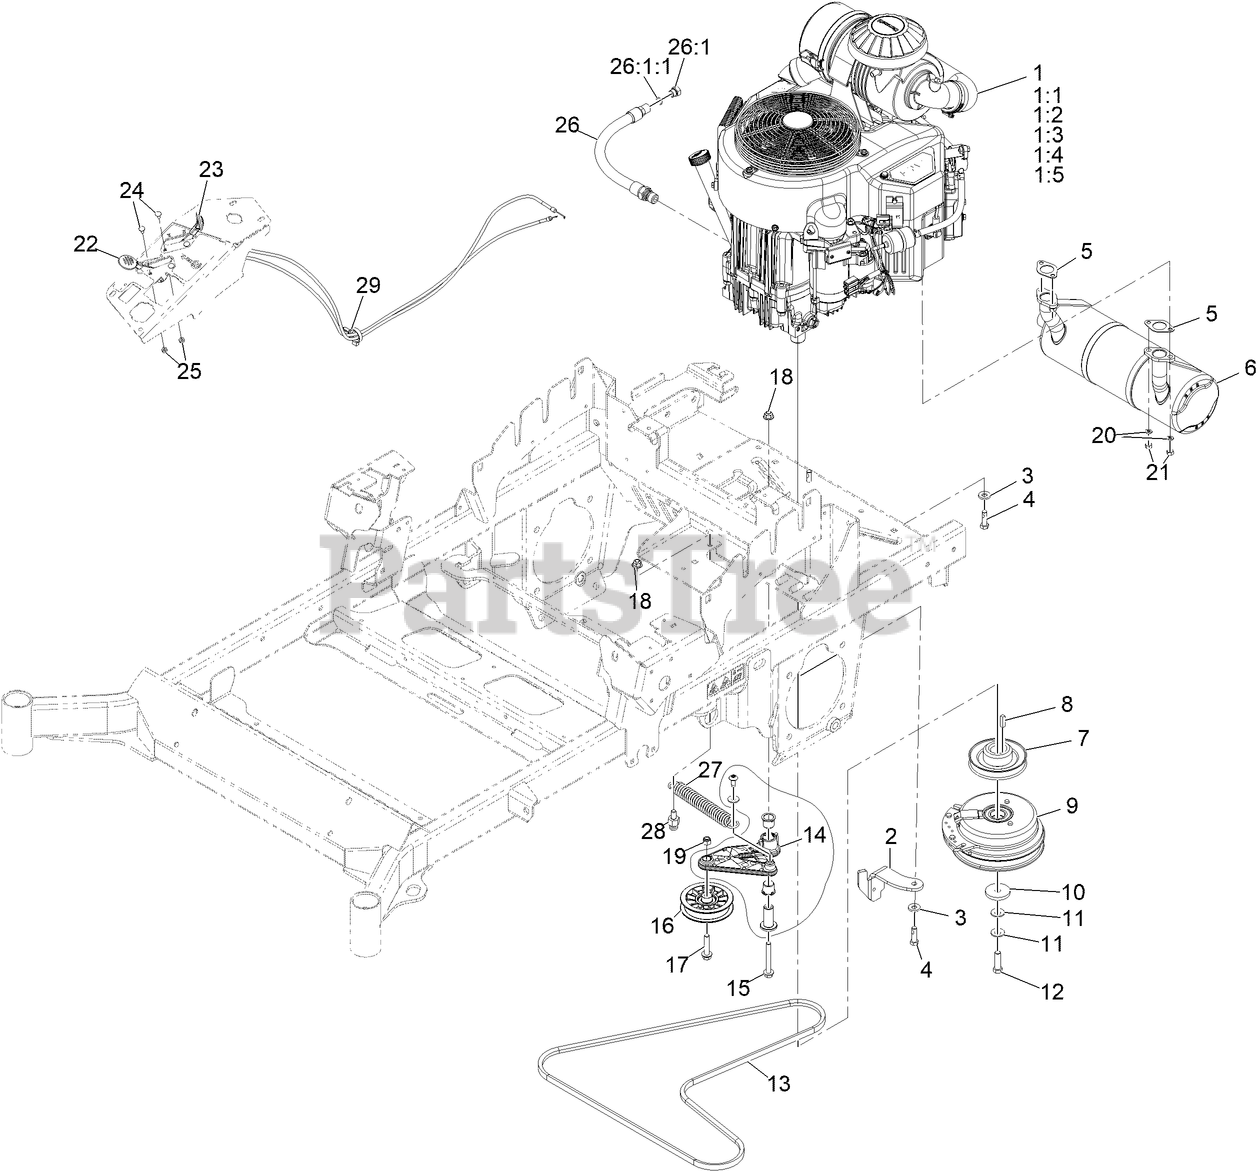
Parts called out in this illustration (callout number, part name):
1	Engine-Kawasaki
1:1	FILTER-OIL KAW
1:2	ELEMENT-FILTER, AIR (OUTE
1:3	ELEMENT-FILTER, AIR (INNE
1:4	FILTER-FUEL
1:5	SPARK PLUG
2	Bracket, Clutch Anchor
3	WASHER-BELLEVILLE
4	Screw-HH, Patch
5	GASKET-EXHAUST
6	MUFFLER, KAWASAKI
7	Sheave, Engine
9	Clutch, Cms-175
10	WASHER-CLUTCH
11	WASHER-SPRING
12	SCREW-HH 7/16-20 X 1 1/2 W/LOCTITE
13	Belt, A-Section
14	ASM, Idler Arm W/ Bushings
15	SCREW-HFH
16	PULLEY-FLAT IDLER
17	SCREW-HHF
18	NUT-HF, NI
19	NUT-LOCK, NI
20	WASHER-LOCK
22	CABLE-CONTROL, THROTTLE
23	CABLE-CONTROL, CHOKE
24	BOLT-CARR
25	NUT-LOCK, NI
26	ENGINE OIL DRAIN HOSE ASM
26:1	PLUG-HH
26:1:1	O-RING
27	Spring, Extension
28	PIN, SPRING ANCHOR
29	CLAMP-HOSE
